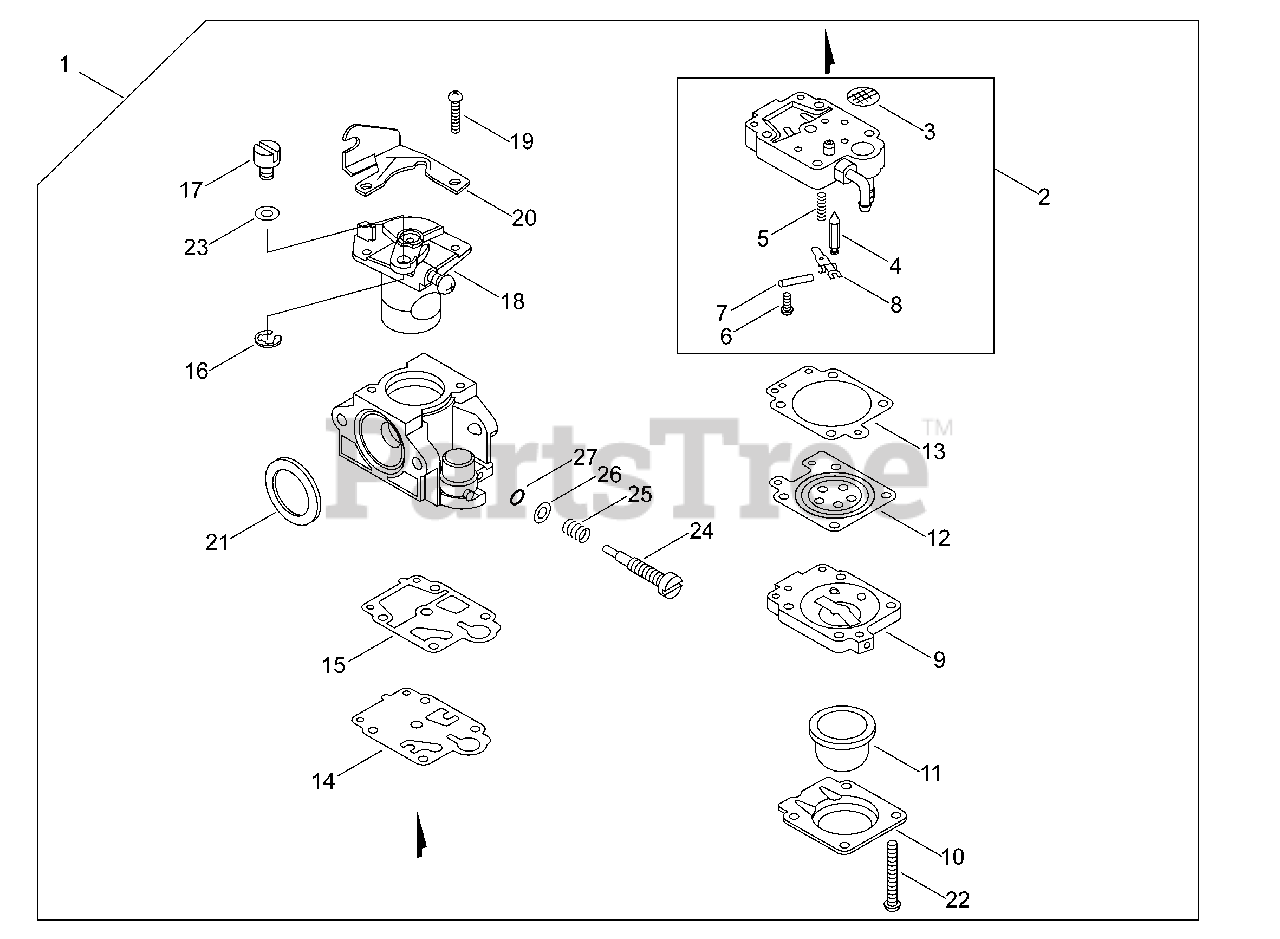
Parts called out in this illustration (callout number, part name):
1	CARBURETOR - WYK-496
2	BODY ASSY, PUMP
3	SCREEN, FUEL INLET
4	VALVE, INLET NEEDLE
5	SPRING, METERING LEVER
7	PIN, METERING LEVER
8	LEVER, METERING
9	BODY ASSY, PURGE
10	RETAINER, PURGE BULB
11	BULB, PURGE
12	DIAPHRAGM, METERING
13	GASKET, METERING DIAPHRAGM
14	DIAPHRAGM, FUEL PUMP
15	GASKET, PUMP
18	VALVE, THROTTLE
20	BRACKET, THROTTLE CABLE
21	RING, PACKING
24	NEEDLE, MIXTURE
25	SPRING, NEEDLE
26	WASHER
27	O-RING
